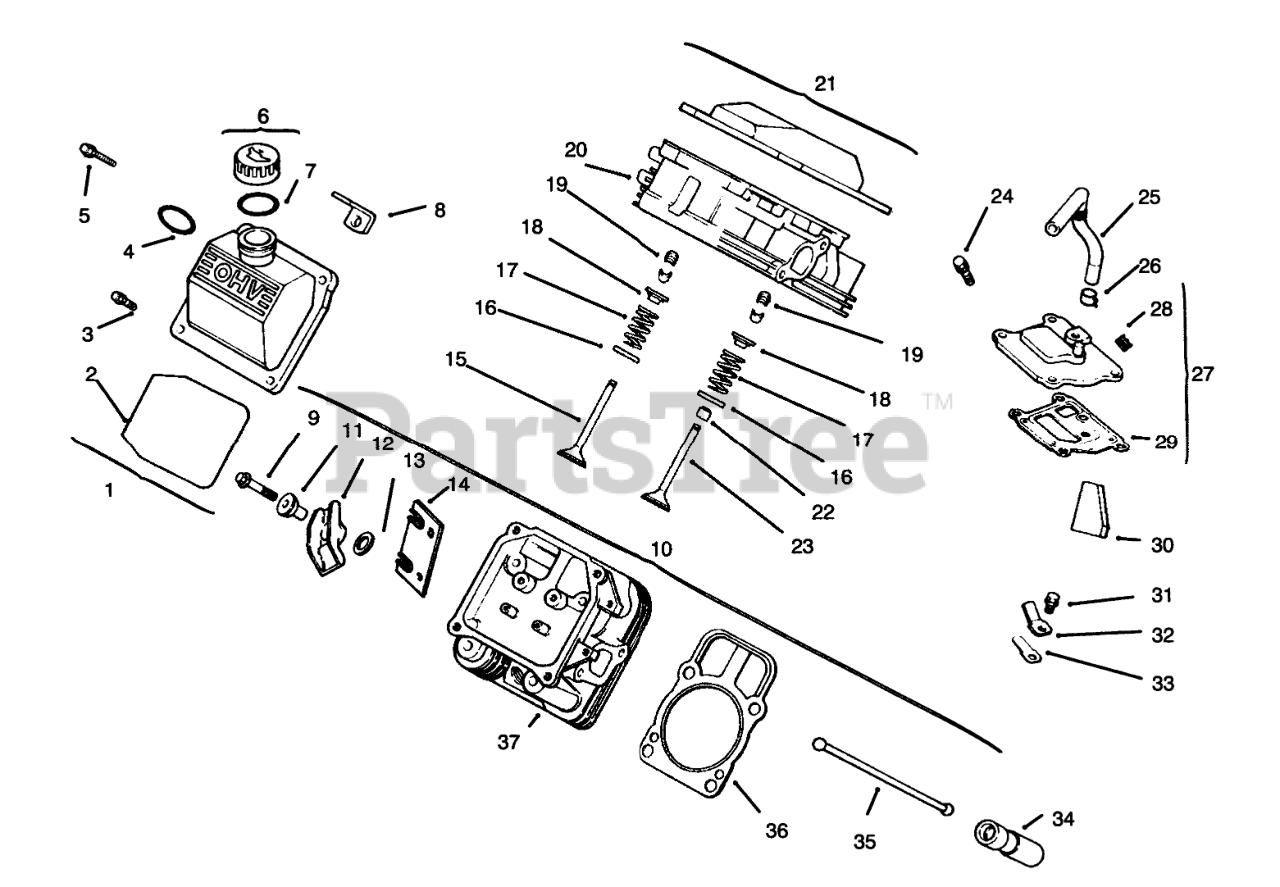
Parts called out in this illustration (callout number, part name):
1	Kit-Valve Cover (Incl. Ref. #2-4)
3	Screw-Shoulder
4	"O"Ring
5	Screw
6	Kit-Oil Fill Cap (Incl. Ref. #7)
7	"O"Ring
8	Strap-Lifting
10	Kit-Valve Train (Incl. Ref. #11-14 & 35)
11	Pivot-Rocker Arm
12	Arm-Rocker
13	Washer
14	Plate-Guide
15	Valve-Exhaust
16	Retainer-Spring
17	Spring-Valve
18	Cap-Valve Spring
19	Kit-Retainer
20	Head Assembly (#1 Cylinder)
21	Kit-Valve Cover (Incl. Ref. #2 & 3)
22	Seal-Valve Stem
23	Valve-Intake
24	Screw
25	Hose-Breather
26	Clamp
27	Kit-Breather w/Plug (Incl. Ref. #28 & 29)
28	Plug
29	Gasket-Breather
30	Filter-Breather
31	Screw
32	Retainer-Reed
34	Lifter-Valve
35	Rod-Push
36	Gasket-Cylinder Head
37	Head-Assembly (#2 Cylinder)
